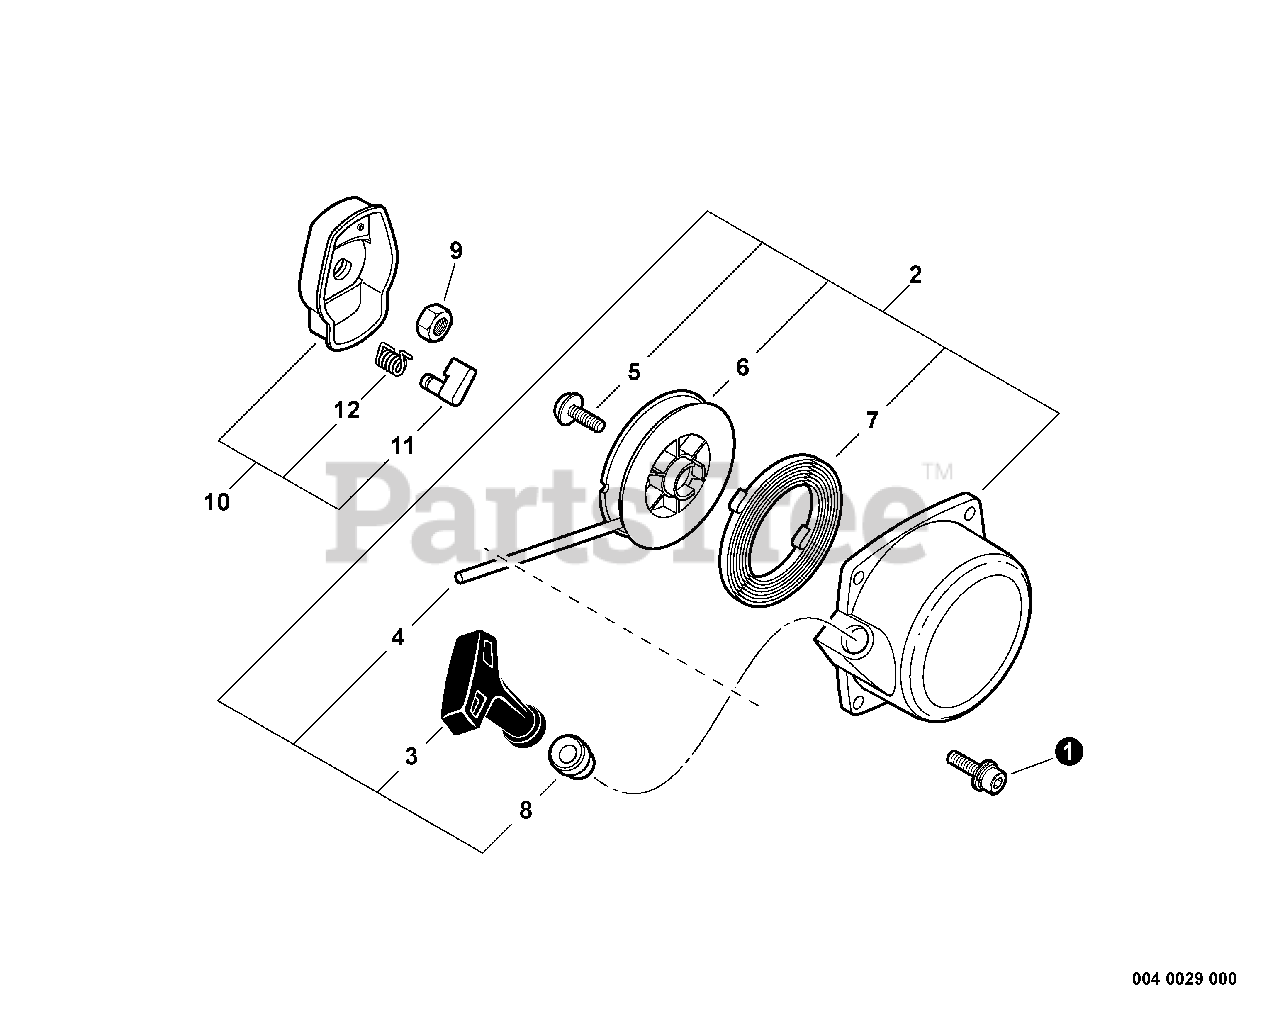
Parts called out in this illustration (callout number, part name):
1	SCREW - 4X16
2	STARTER ASSY
3	GRIP, STARTER
4	ROPE, STARTER - 3X1000
6	REEL, ROPE
7	SPRING, REWIND
8	GUIDE, ROPE
10	STARTER PAWL ASSY
11	PAWL, STARTER - BLACK
12	SPRING, RETURN
